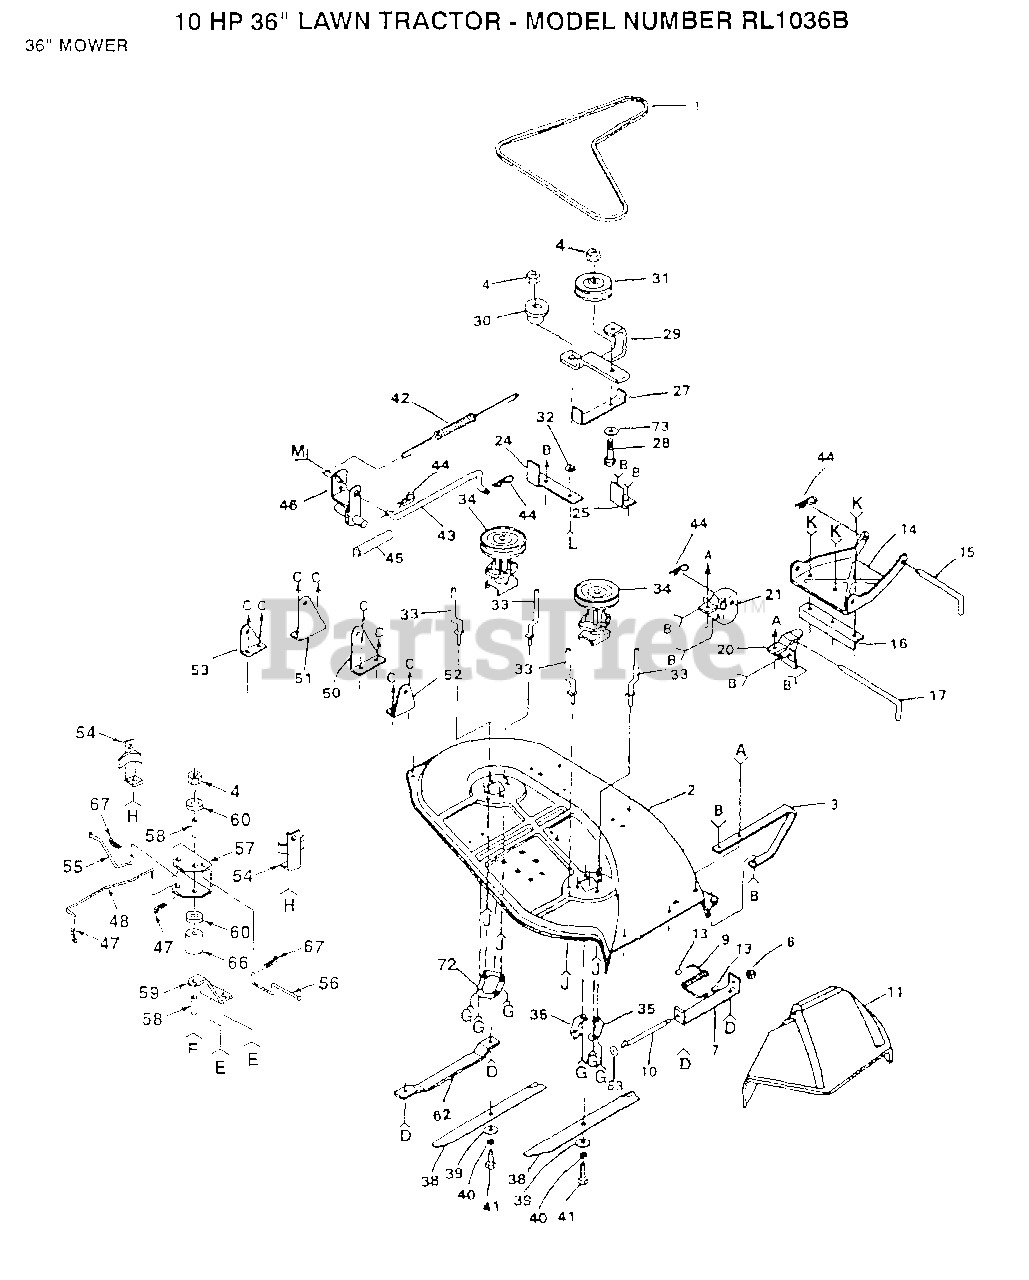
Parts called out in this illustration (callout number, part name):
1	BELT-V.79.1.MWR
5	WASHER M
6	BOLT
8	NUT PUSH M
10	ROD-HINGE T
11	DEFLECTOR SHLD LT
13	CAP-SLEEVE LT
14	LINK.PARALLEL
15	"ROD, FRT. PARAL T"
16	LINK STOP
17	HINGE PIN T
20	BRACKET RH LT
21	BRACKET LH T
22	BOLT
24	SUPPORT ARM T
25	STOP T
30	SPACER RETAINER
32	"WASHER, WEAR LT"
33	BELT KEEPER LT
35	SUPPORT PLATE LT
36	SCREW
37	SCREW
38	"BLADE.38"" HI-LI"
39	WASHER
41	BOLT.3/8-24X1-1/2
44	SPRING.RETAINER
45	SPACER T
48	ROD BRAKE LT
49	BOLT
52	"BRKT,SUSP RH T"
53	"BRKT,SUSP REAR LH"
54	BRAKE LT
55	"ROD, BRAKE LH LT"
56	ROD BRAKE LT
57	"BRK,BRAKE,PVT LT"
58	SPACER BRAKE LTV
59	BRACKET SUPT LTV
60	WASHER
61	BOLT
62	RUNNER-LH M
63	WASHER
64	BOLT.3/8-14X1.25
69	BOLT LT
70	WASHER T
72	SUPPORT T
73	WASHER
